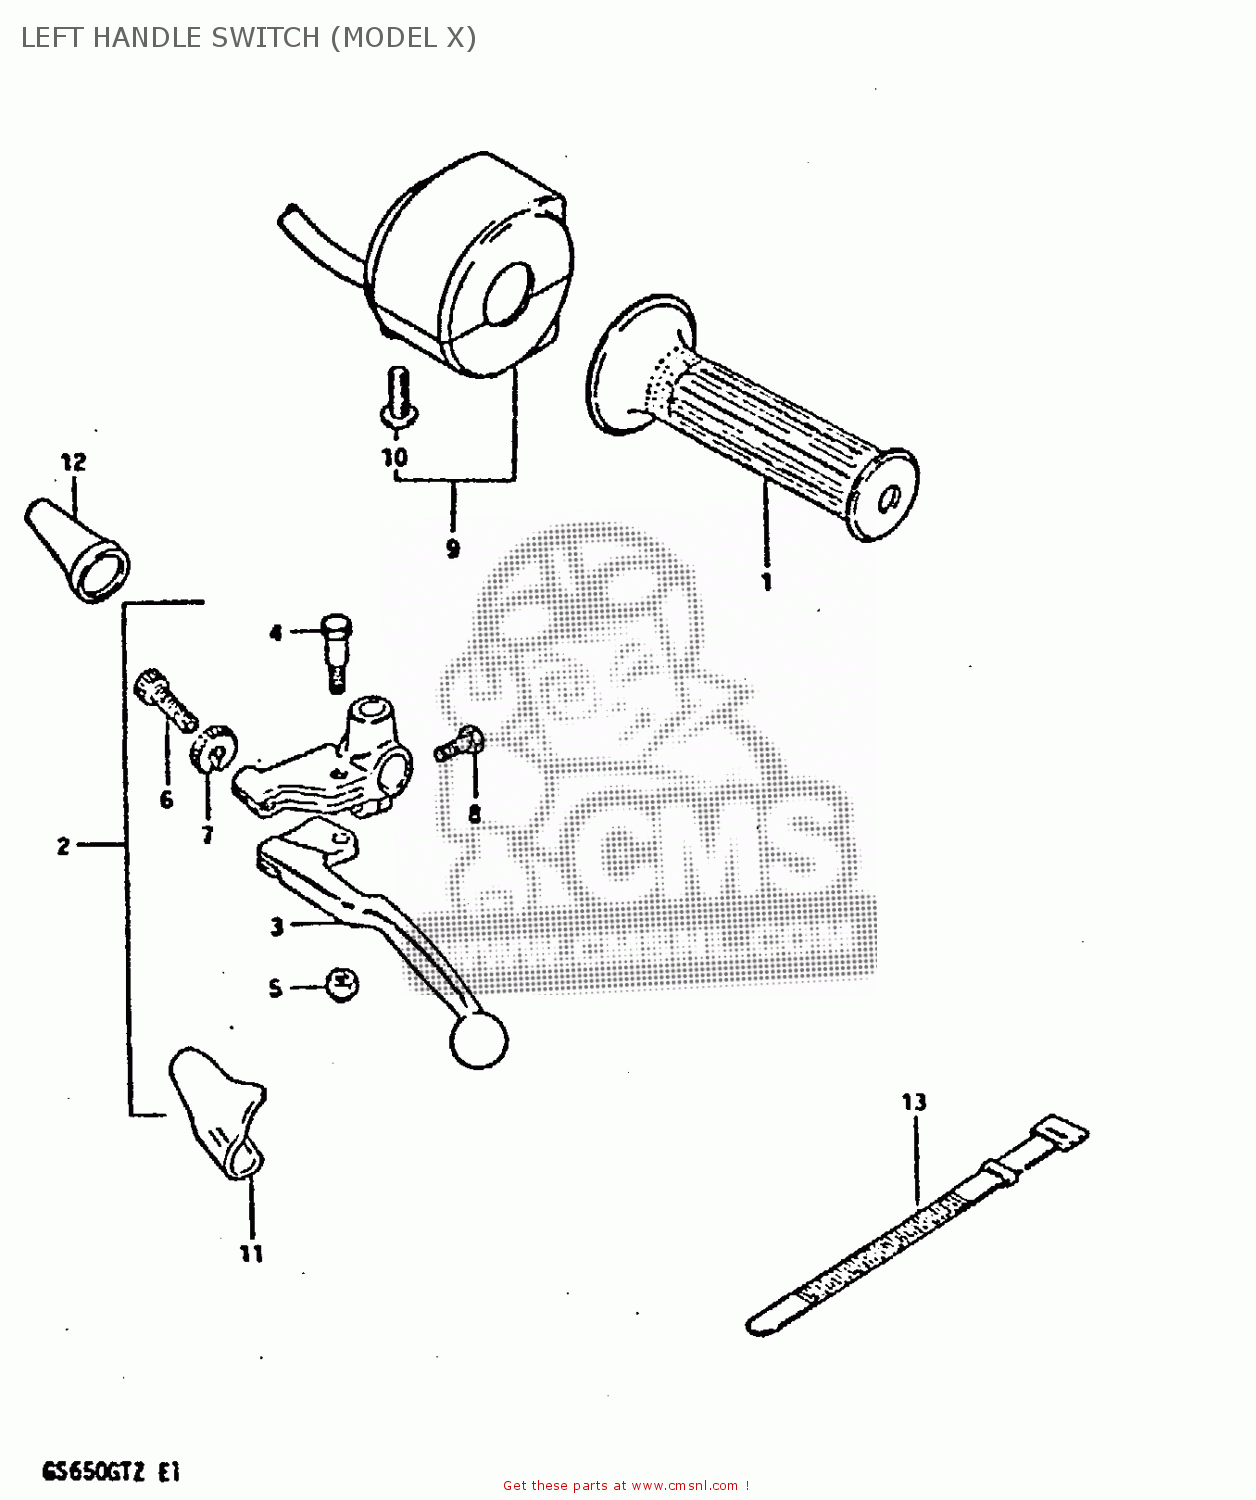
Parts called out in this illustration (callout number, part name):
1	GRIP,LEFT
2	LEVER ASSEMBLY
3	LEVER,CLUTCH
4	BOLT,LEVER
5	NUT 6MM
6	ADJUSTER,CABLE
7	NUT,CABLE ADJUSTER
8	BOLT
9	SWITCH ASSY, HANDLE LH
10	SCREW
11	COVER,CLUTCH LEVER
12	BOOT,CLUTCH CABLE
13	CLAMP(L:120)
